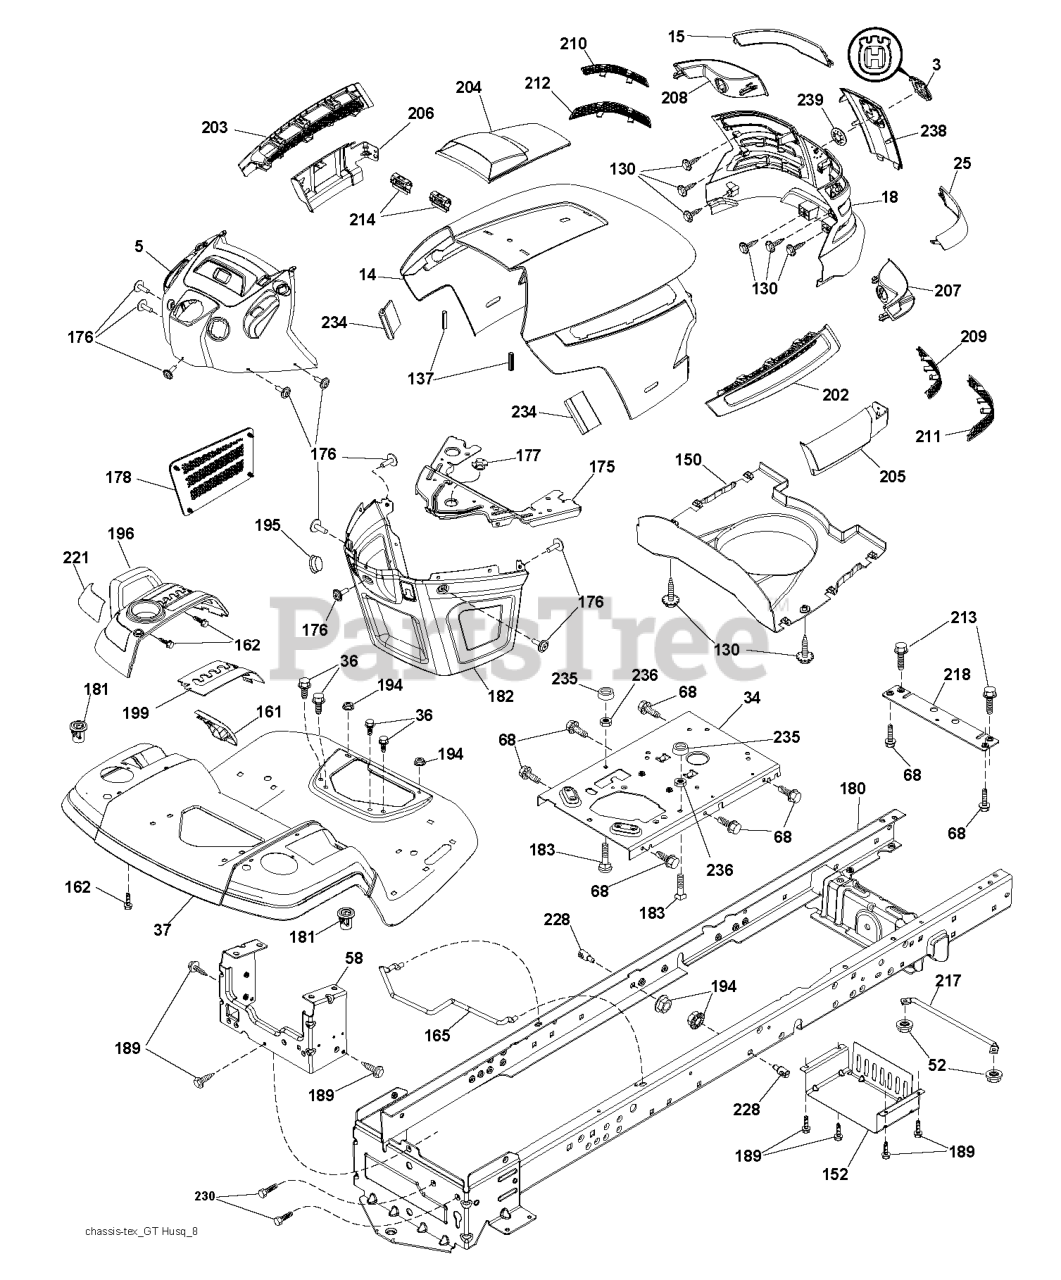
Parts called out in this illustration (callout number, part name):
3	RP LOGO
5	DASH.ASM.HUSQ.GT.E.RECT.W/CK
14	HOOD
15	LENS.LH.TEX.GT.HUSQ.CL
18	GRILL.ASM.HUSQ.TG/CRD.W/TRIM
25	LENS.RH.TEX.GT.HUSQ.CL
34	PLATE.ENGINE.WELDED.CHASSIS
36	SCREW 5/16"
37	FENDER.PNT.TX.GT.CH/FW.ORANGE
52	LOCKNUT
58	DRAWBAR.UPPER.2PC,LRG.FENDER
68	Screw 5/16-18 x 1/2 Hex, Self Tapping 5/16-18 x 1/2
130	SCREW.#10 X 0.750.BOS
137	BUMPER DASH
150	AIR.DUCT.HOOD.TEX.GT.HUSQ
152	SHIELD.BROWNING.W/TEX
161	CONSOLE.FUEL.WINDOW.HU
162	SCREW.HI-LO.CONSOLE
165	SUPPORT.TANK.REAR.W/TEX
175	PLATE.CROSSMEMBER.HUSQ
176	SCREW.#10-24X5/8.RN.QU
177	BUSHING, STEERING
178	CARGO.ASM.NET.TXGT.W/C
180	CHASS.WLDMNT.TL.12GA/2P.48/54
181	BUSHING.MNT.FEND.CRGO.
182	DASH.LOWER.COMMON.12V.ADAPTOR
183	BOLT.5/16-18X1-1/4 FULL.THREAD
189	SCREW
194	NUT LOCK HEX FLANGE 5/16-18
195	PLUG.HOLE.DASH.LOWER.12V.BLK
196	RP CONSOLE.ASM.DECKLFT.W/
199	PLATE.DECK.LIFT.HUSQVARNA.GT
202	VENT.SIDE.HOOD.HUSQ.RH.GREY
203	VENT.SIDE.HOOD.HUSQ.LH.GRAY
204	HOOD VENT
205	SKIRT.HOOD.SIDE.HUSQ.RH.GREY
206	SKIRT.HOOD.SIDE.HUSQ.LH.GREY
207	BEZEL.RH.TEX.GT.HUSQ
208	BEZEL.LH.TEX.GT.HUSQ
209	INSERT.HEX.GRILL.HUSQ.GREY
210	INSERT.HEX.GRILL.HUSQ.
211	INSERT.HEX.GRILL.HUSQ.
212	INSERT.HEX.GRILL.HUSQ.
213	BOLT
214	CLIP.RETAINER.TINNER.
217	ROD.PIVOT.HOOD
218	X-PIECE.HOOD.STOP.NON/
221	REFLECTOR.LH.TEX GT HU
228	STUD.FASTNER.W/ANTI-ROTATE
230	BOLT.SHOULDER
234	BUMPER.HOOD.TEX.HUSQVARNA
235	SPACER FENDER
236	NUT.CENTERLOCK.5/16-
238	TRIM.HUSQ.TG/CRD.SERVICE
239	NUT PUSH M
